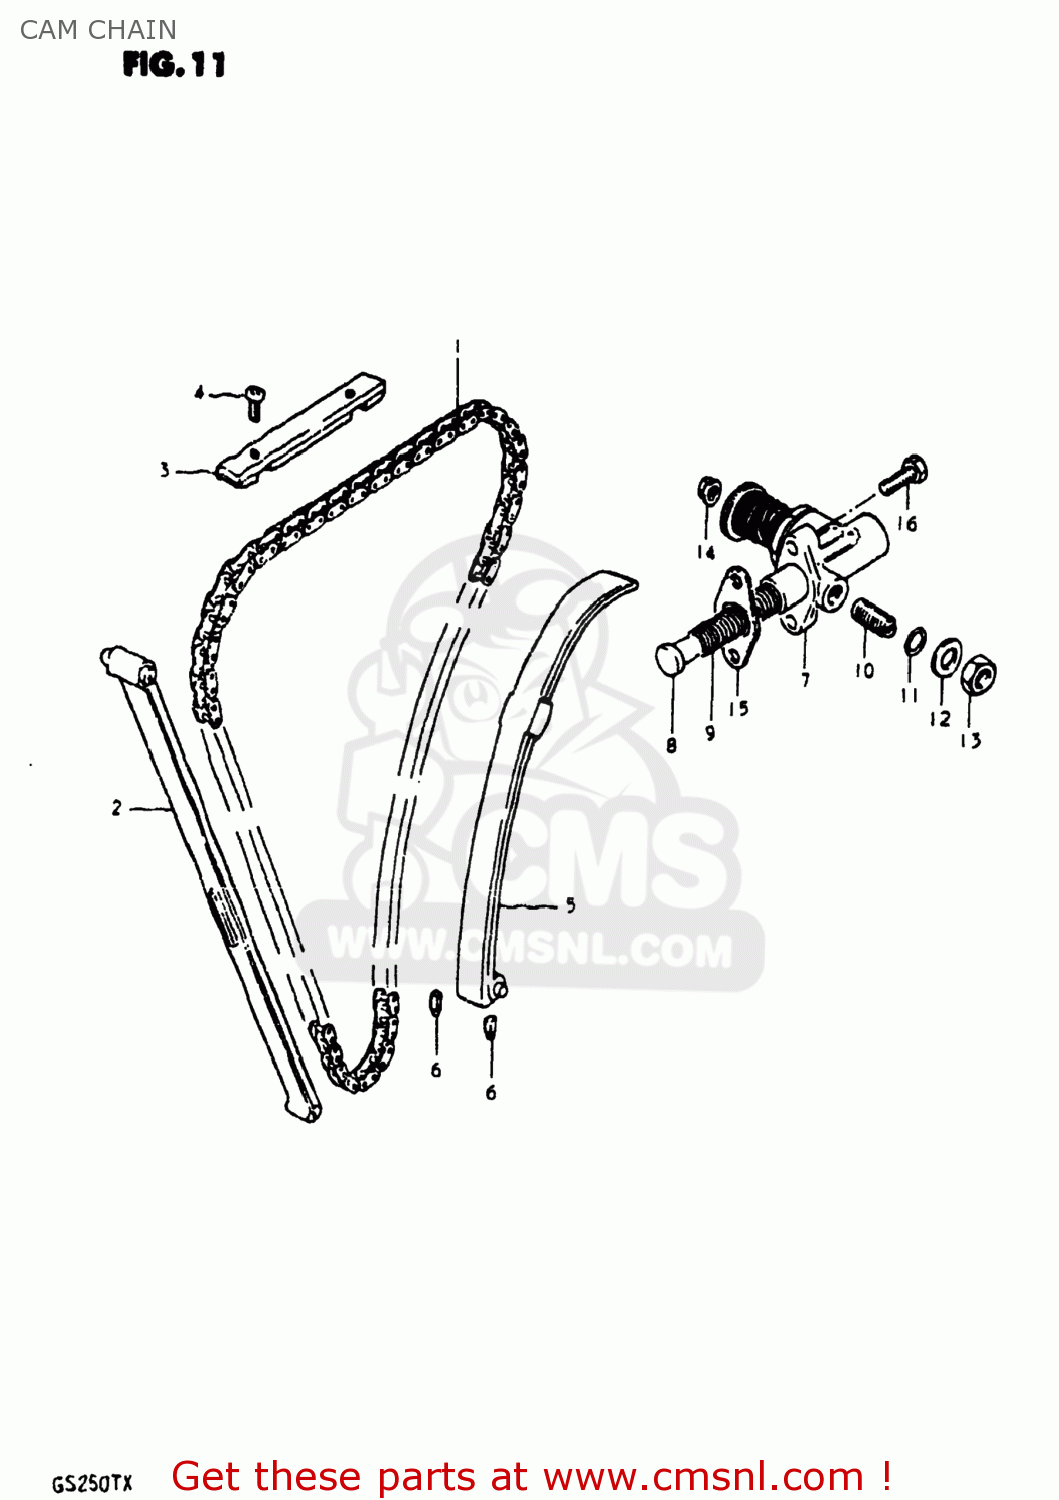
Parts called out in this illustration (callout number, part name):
1	CHAIN,CAMSHAFT DRIVE
2	GUIDE,CAM CHAIN NO.1
3	GUIDE,CAM CHAIN NO.3
4	SCREW
5	TENSIONER,CAM CHAIN
6	CUSHION,CAM CHAIN TENSIONER
7	ADJUSTER ASSEMBLY,TENSIONER
8	ROD,PUSH
9	SPRING
10	SCREW
11	O-RING
12	WASHER
13	NUT
14	NUT
15	GASKET,TENSIONER ADJUSTER (MCA)
16	SCREW (6X25)
